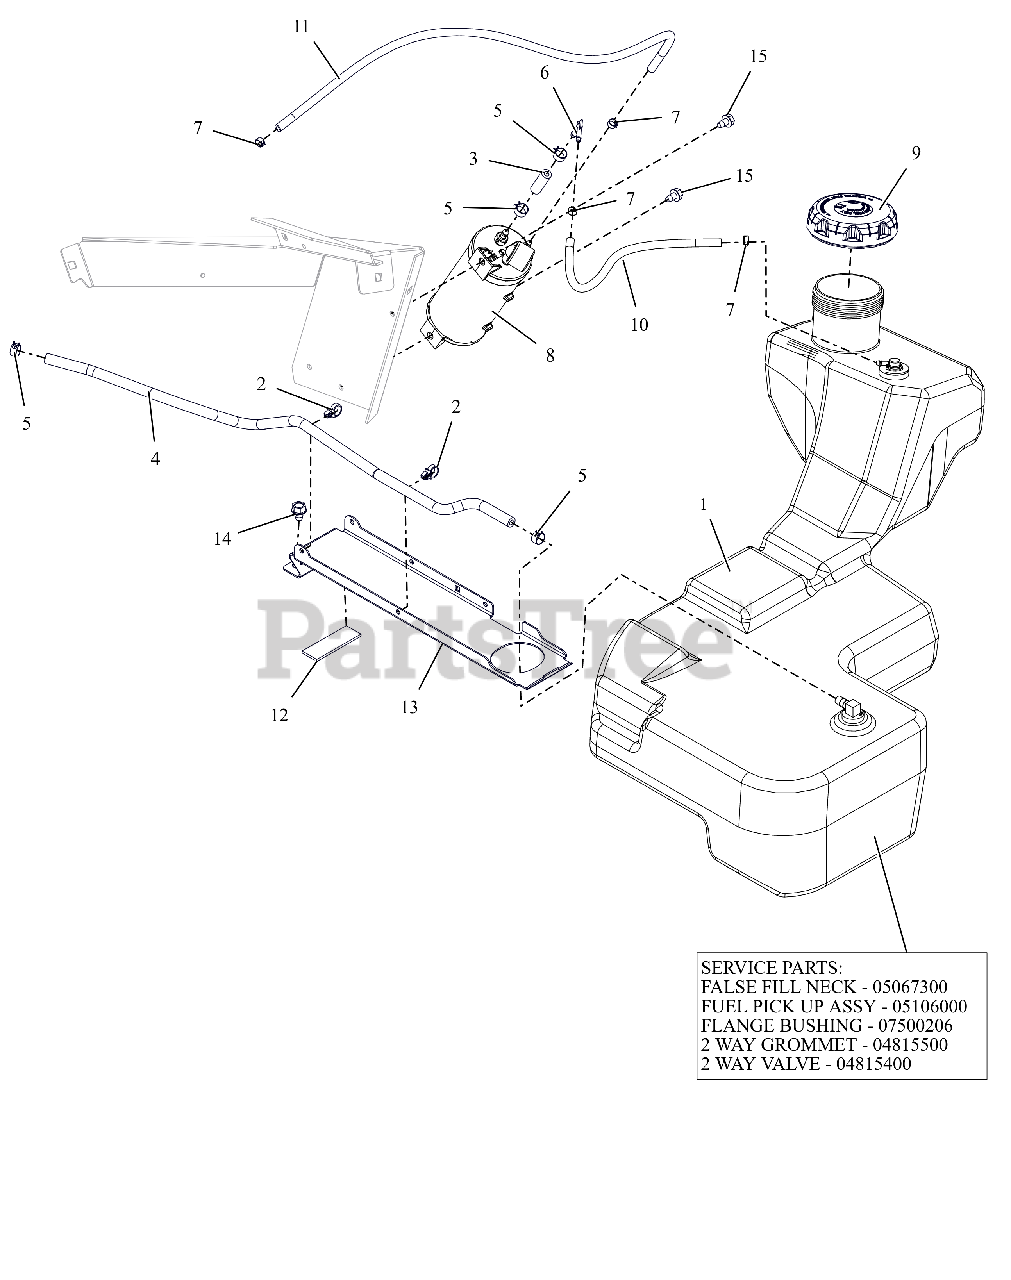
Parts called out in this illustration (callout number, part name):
1	ASM, HD FUEL TANK
1	INSERT, FUEL NECK FALSE FILL
1	ASM, HD FUEL PICK-UP
1	BSHG-FLG .375X1.062X.625 NITR
1	GROMMET, 2-WAY
1	VALVE, 2-WAY
2	ROUTING CLIP (1/2" ID)
3	HOSE, .25 LOW-PERM BULK GAS
4	HOSE, .25 LOW-PERM BULK GAS
5	CLAMP, FUEL LINE
6	FITTING-3/16X1/4 90DEGREE VAC
7	CLAMP-HOSE, SPRING .188
8	CANISTER, 400 CC CARB
9	CAP, FUEL VENTIN AUTOLOCK
10	HOSE, .188 30R7 BULK
11	HOSE, .188 30R7 BULK
12	PAD,RBR 1.0"X3.0" W/ADHESIVE
13	BRKT, FUEL TANK HOLD DOWN
14	SCR,TAP .375-16X.50 HWH TR ZCC
15	SCR,TAP .312-18X.50 HWH TR ZCC
